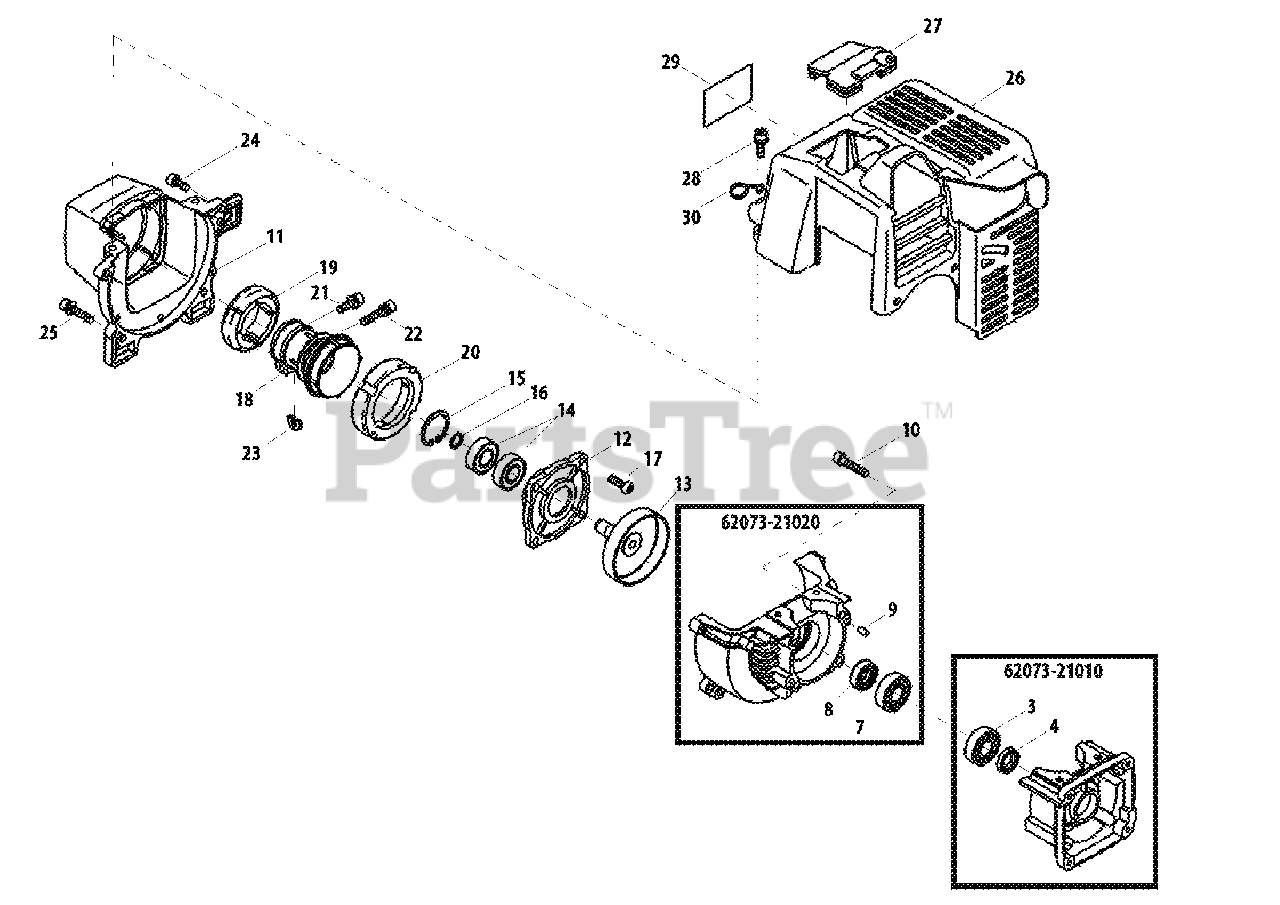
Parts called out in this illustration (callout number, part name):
3	BEARING, BALL 6201C3
4	SEAL, OIL 12
7	BEARING, BALL 6201C3
8	SEAL, OIL 12
9	PIN, LOCATING 5×10
10	BOLT 5×25
11	CASE, FAN
12	CASE, CLUTCH
13	DRUM, CLUTCH
14	BEARING, BALL 6001 DDU C3
15	RING, SNAP Ø28
16	RING, SNAP Ø12
17	BOLT M5×16
18	JOINT
19	HOLDER, FRONT CUSHION
20	HOLDER, REAR CUSHION
21	BOLT M5×16
22	BOLT M6×28
23	SHIM
24	BOLT M5×18
25	BOLT SS M5×30
26	COVER, ENGINE
27	COVER
28	BOLT M5×16
29	LABEL - TRADE
30	HOLDER, THROTTLE CABLE
6207321010	CRANKCASE ASSY - REAR
6207321020	CRANKCASE ASSY - FRONT
